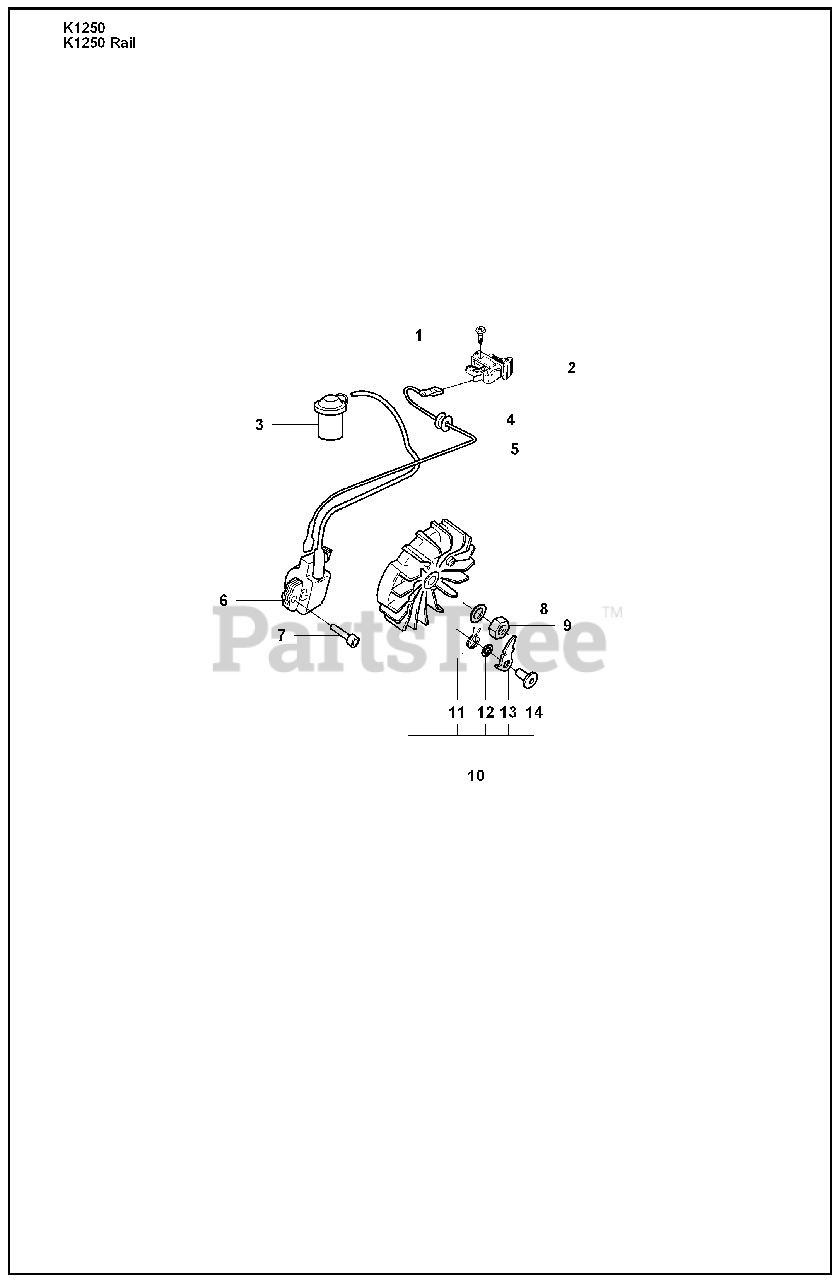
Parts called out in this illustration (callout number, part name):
1	SCREW
2	STOP SWITCH
3	SPARK PLUG CAP
4	CABLE GROMMET
6	IGNITION SYSTEM
8	SPRING WASHER
10	FLYWHEEL ASSY
12	WASHER STEEL
